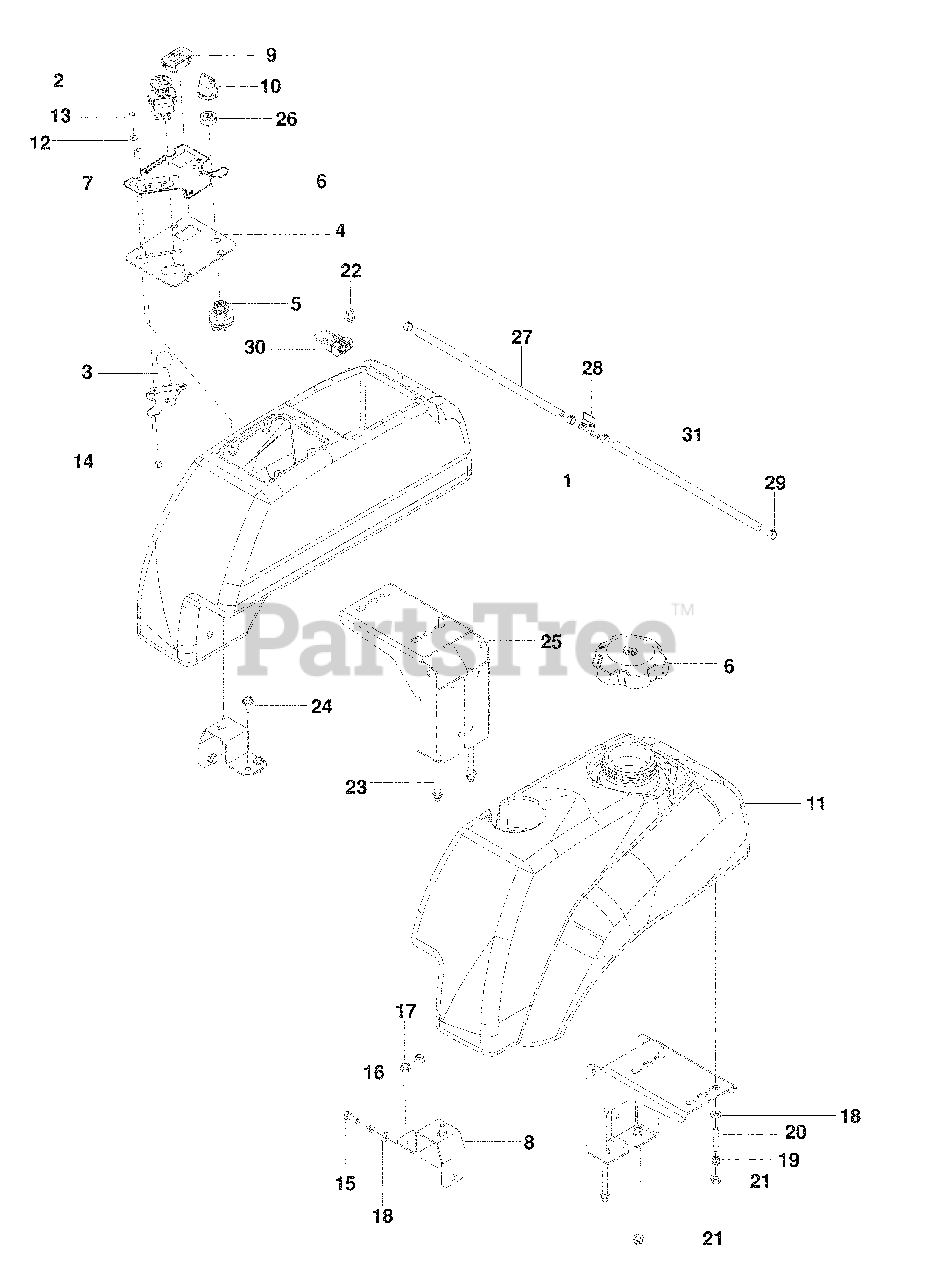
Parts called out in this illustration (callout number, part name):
2	SWITCH, PTO 10 AMP
3	CABLE, THROTTLE
4	CONSOLE PLATE
5	SWITCH, IGNITION
7	DECAL, CONSOLE
8	SUPPORT, TANK
9	HOUR METER
10	KEY, IGNITION
11	TANK, FUEL
12	WASHER #10 FLAT
13	SCREW #10-24 x ½ SLT HEX
14	NUT #10-24 HEX NYLOC
15	BOLT, HEX 5/16-18 x ¾
16	WASHER 5/16 SLW
17	HHFS 5/16-18 x 1¼ TPBLT
18	WASHER 5/16 SAE FLAT
21	NUT 5/16-18 FLANGE NYLOC
22	TIE, PLASTIC
23	HHFS 5/16-18 x 3¾
24	BOLT 5/16-18 x ¾ THD FRM
25	MOUNT, TANK
26	CAP, IGNITION SWITCH
27	FUEL LINE 13"
28	VALVE, FUEL
29	CLAMP, HOSE
30	PLUG, TIMER
31	FUEL LINE 18"
